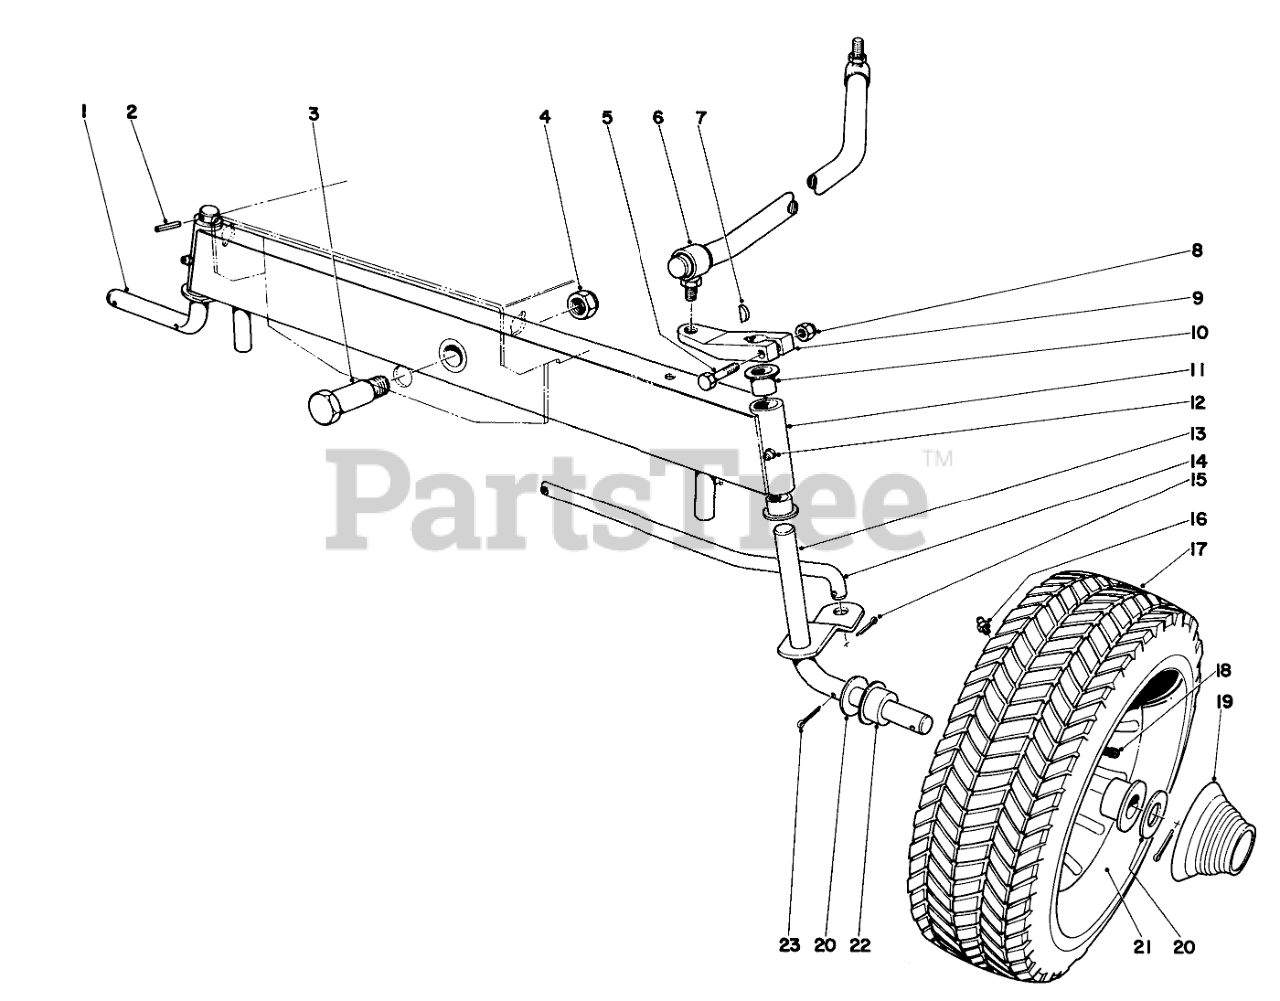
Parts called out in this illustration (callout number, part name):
1	Spindle
2	PIN-SPRING
3	Shoulder Bolt
4	1/2-13 CONELOCK NUT
5	SCREW-HH
6	Drag Link
7	KEY-WOODRUFF
8	NUT-LOCK, CONE
9	Arm Steering
10	BUSHING-FLANGE
11	Front Axle (Incl. Ref. #10)
12	GREASE FITTING
13	Spindle
14	Tie Rod
15	PIN-COTTER
16	FITTING-GREASE
17	Tire Turf King
18	STEM-VALVE
19	FRONT HUB CAP
20	WASHER-FLAT
21	Rim (Incl. Ref. #22)
22	BUSHING
23	PIN-COTTER
